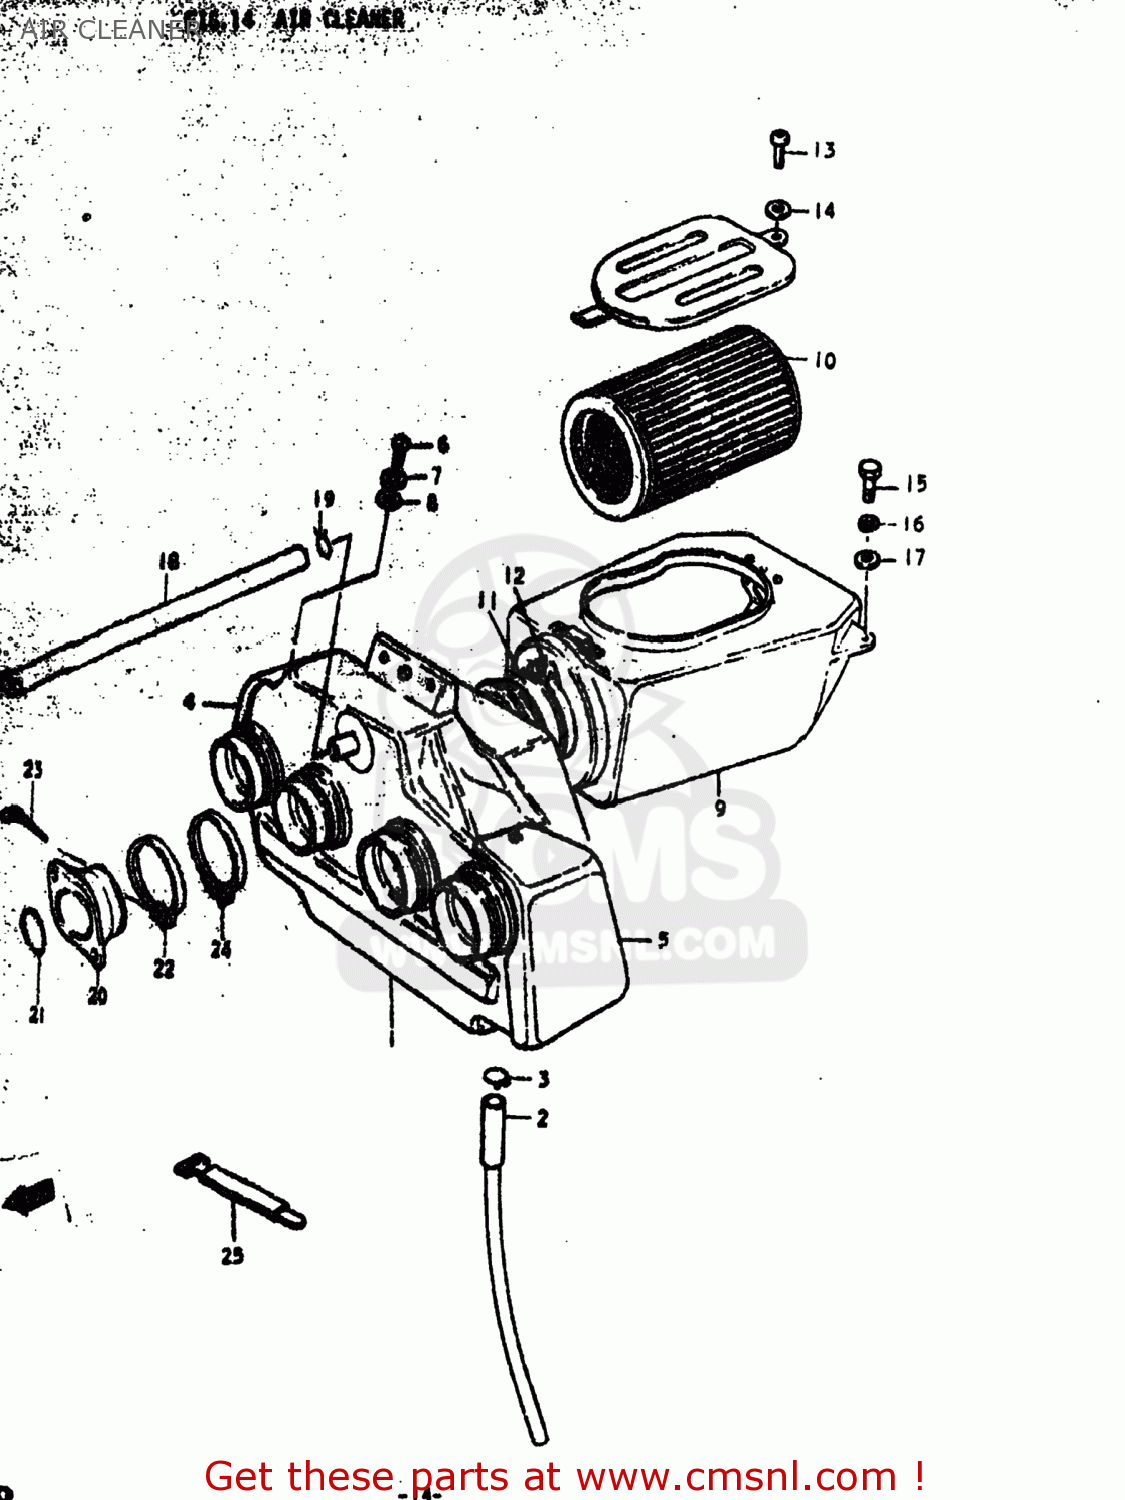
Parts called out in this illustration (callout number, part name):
1	CASE COMP,AIR CLEANER
2	HOLDER,FILTER
3	HOSE,AIR CLEANER
6	SCREW
7	LOCK WASHER
8	WASHER
9	CASE ASSEMBLY,AIR CLEANER
10	FILTER,AIR CLEANER
11	HOSE,AIR CLEANER
12	BAND
13	SCREW
14	WASHER
15	BOLT, UPPER
16	LOCK WASHER
17	WASHER
18	HOSE
19	CLIP
20	PIPE,INTAKE
21	O RING(D:2.4,ID:31.7)
22	CLAMP
23	SCREW
24	CLAMP
25	CLAMP(L:120)
